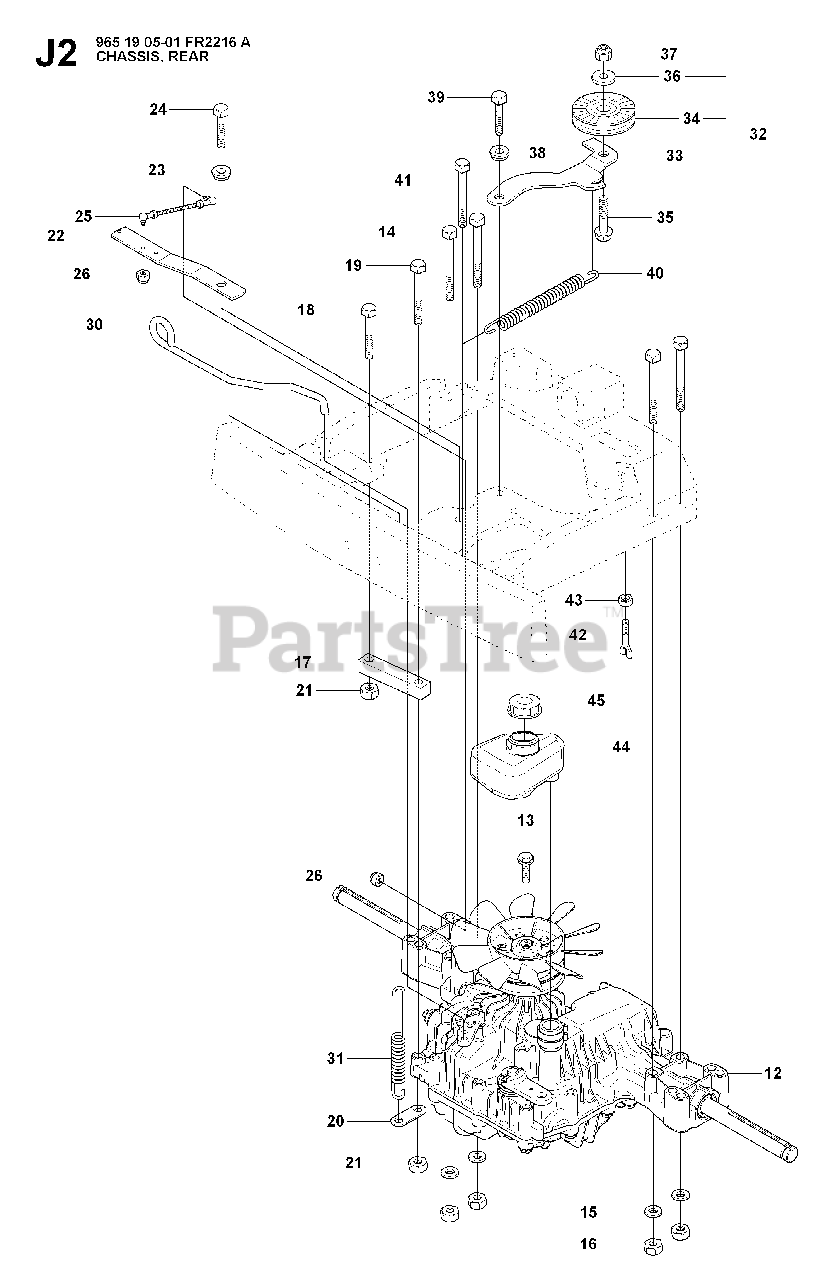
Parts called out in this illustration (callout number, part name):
12	HYDROSTAT
15	WASHER BRB 8.4X17
16	NUT
20	CONNECTOR
21	NUT
23	WASHER
24	SCREW 8X20
26	LOCKNUT M5
31	SPRING
32	TENSIONER
33	TENSIONER
37	LOCKNUT M8
38	WASHER
39	SCREW 8X20
